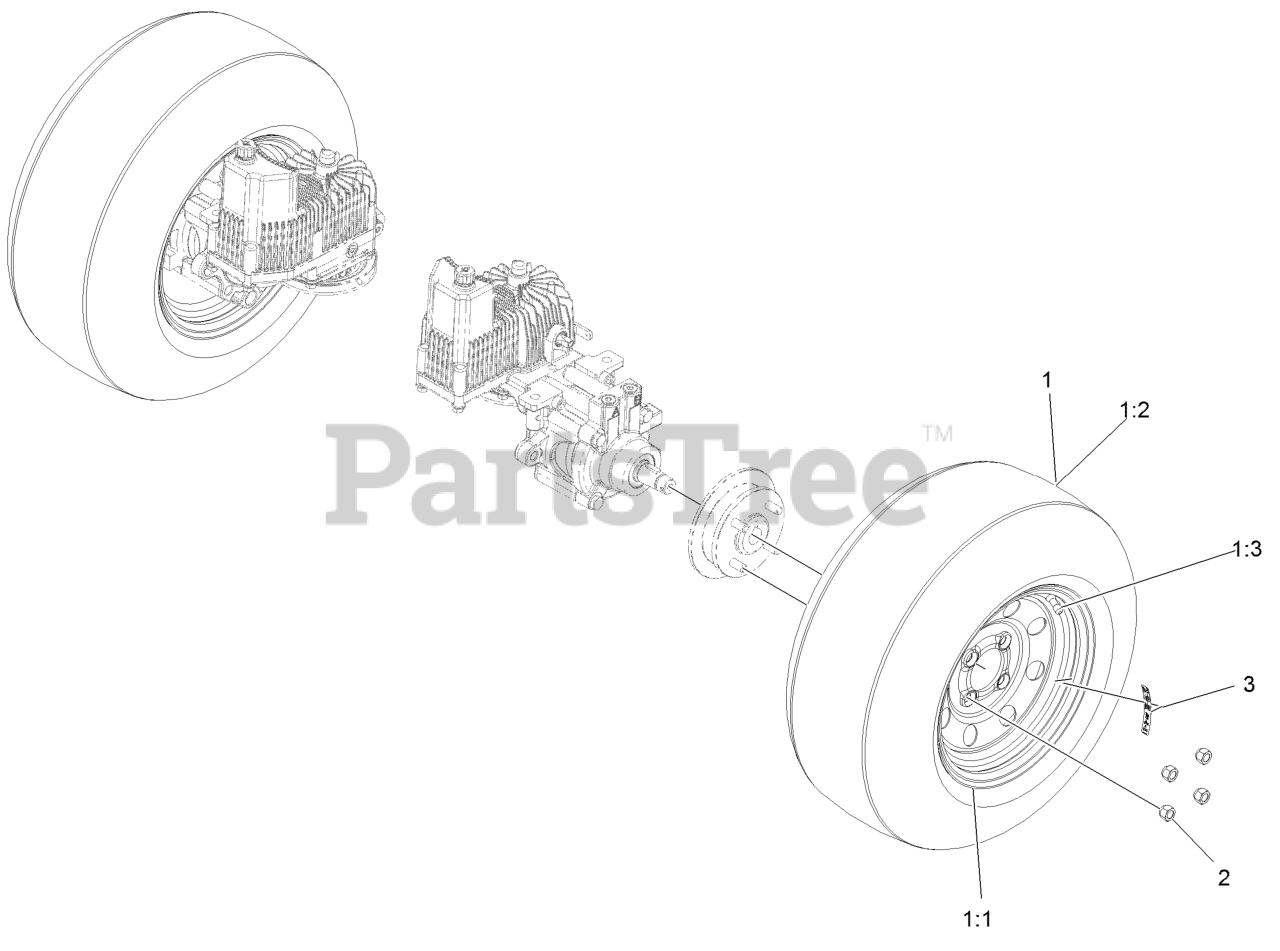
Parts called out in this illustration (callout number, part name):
1	WHEEL AND TIRE ASM
1:1	ASM, RIM
1:2	TIRE-DRIVE, 23X9.5-12
1:3	Stem-Valve
2	NUT-LUG
3	DECAL-TORQUE, WHEEL HUB LUG
